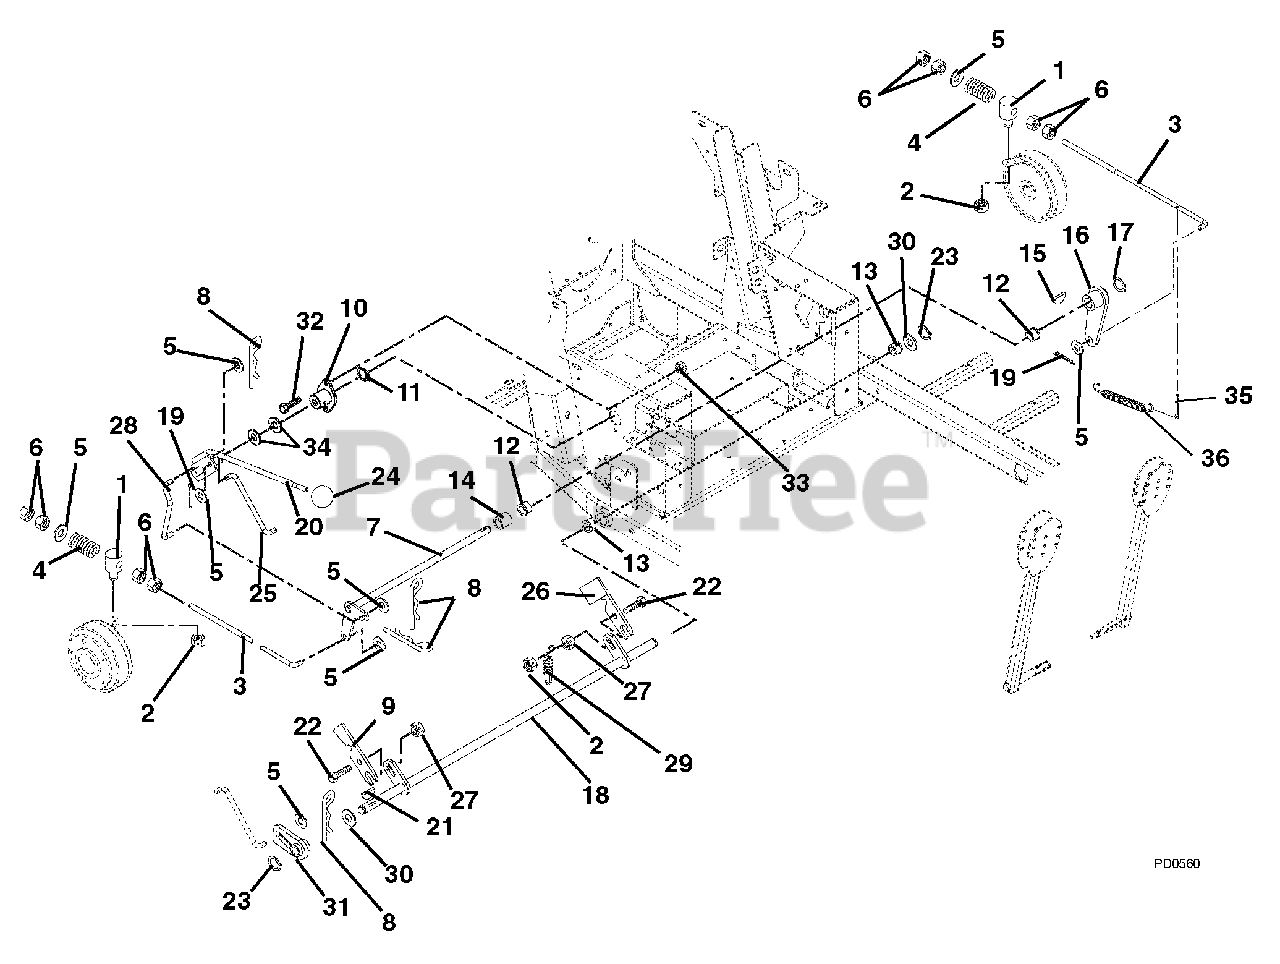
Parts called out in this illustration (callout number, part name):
1	Pivot, Brake Rod
2	Nut, Locking Center .31-18
3	PTO Link Rod
4	Spring, Compression .142 x .710 x 1.75
5	Washer, Flat Steel .406 x .812 x .065
6	Nut, Hex .38-16
7	Shaft, Brake Cross
8	Pin, Hair
9	Slide, Interlocking Brake
10	Bushing, Flange
11	Ring, Retaining External .625 x .05
12	Bushing, Flange Nylon .762 x 1.00 x .58 x 1.48
13	Bushing, Flange .515 x .75 x .745 x 1.00
14	Bushing, Sleeve .75 x 1.00 x .75
15	Key, Woodruff .19 x .75 Hard #9
16	Arm, Brake
17	Ring, Retaining External .69 x .077
18	Weldment, Mechanical Brake
19	Pin, Cotter External .09 x .75
20	Weldment, Handle
21	Key, Woodruff .13 x .63
22	Bolt, Round Head Square Neck .31-18 x 1.25 Grade 5
23	Ring, Retaining External .50 x .05
24	Grip, Handle
25	Linkage, Brake Actuating
26	Interlock, Safety Switch
27	Nut, Locking Top Flange .31-18
28	Linkage, Brake Actuating
29	Spring, Tension .048 x .44 x 1.75
30	Washer, Flat Steel .505 x 1.00 x .062
31	Weldment, Parking Brake Hub
32	Bolt, Hex .31-18 x .75 Grade 5
33	Nut, Locking Top Flange .31-18
34	Washer, Flat Steel .630 x 1.25 x .062
35	Pin, Cotter .12 x .75 Extended Prong Square Cut
36	Spring, Extension
